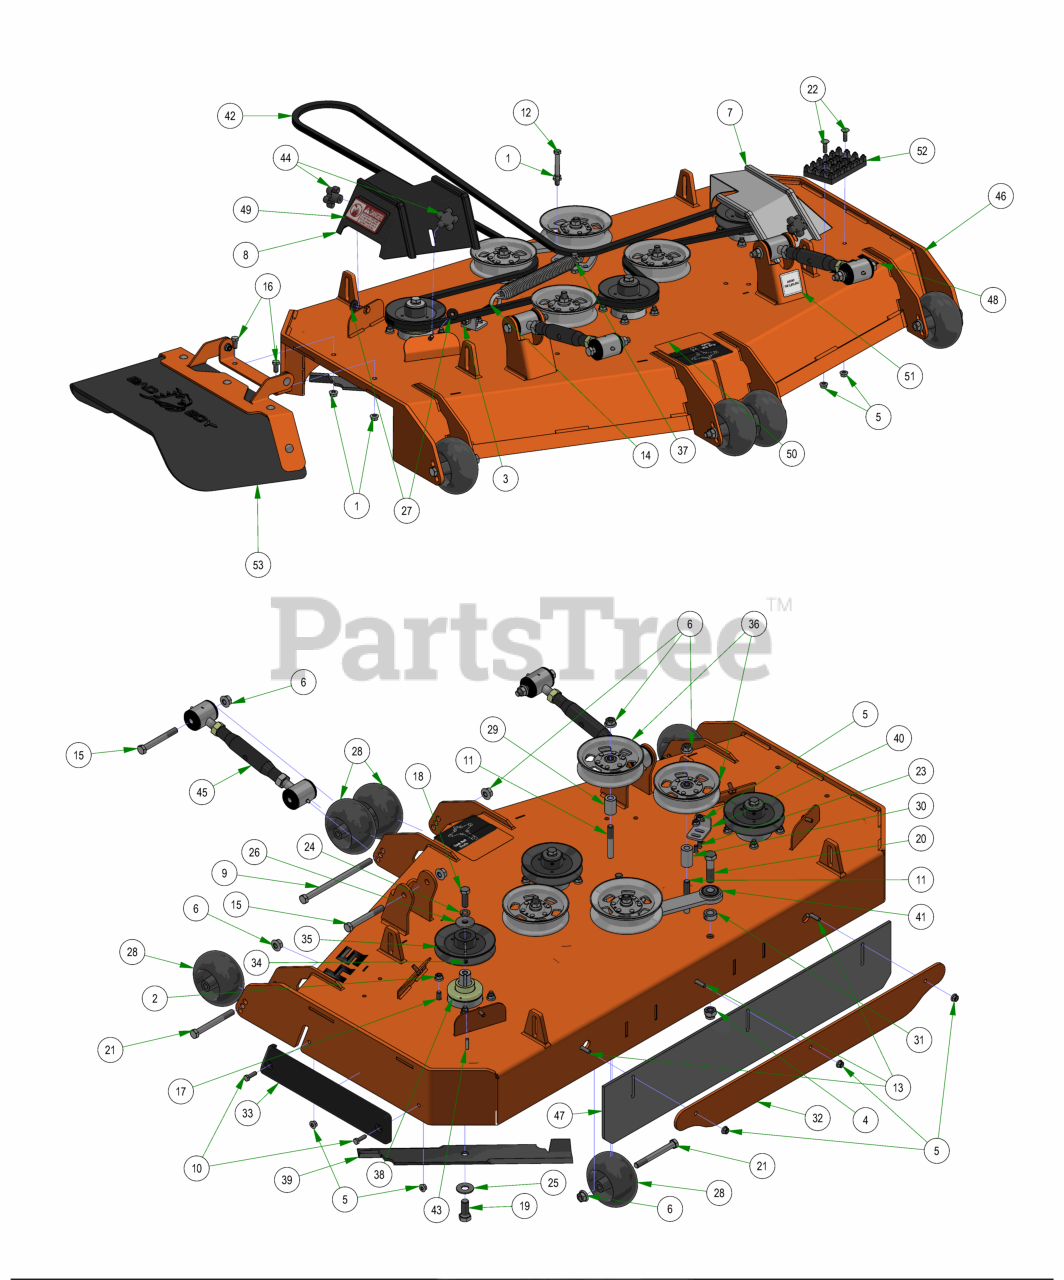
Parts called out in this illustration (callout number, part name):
1	3/8-16 HEX SERRATED FLANGE NUT HARD/ZINC
2	3/8-16 NYLON INSERT FLANGE LOCKNUT (GR.F) ZINC
3	3/8-16 HEX NUT ZINC
4	5/8-11 NYLON INSERT LOCKNUT ZINC
5	5/16-18 NYLON INSERT FLANGE LOCKNUT ZINC
6	1/2-13 NYLON INSERT FLANGE LOCKNUT ZINC
7	2019 54" Left Outlaw Gen2 Pulley Cover
8	2019 54" Right Outlaw Gen2 Pulley Cover
9	1/2-13 X 8 HEX CAP SCREW GR 5 ZINC
10	5/16-18 X 1 HEX CAP SCREW (GR.5) ZINC
11	1/2-13 X 3-1/2 HEX FLANGE BOLT (GR.8) ZINC
12	3/8-16 X 3 HEX CAP SCREW (GR.5) ZINC
13	5/16-18 X 1-1/4 CARRIAGE BOLT ZINC
14	4" 3/8-16 Eye Bolt
15	1/2-13 X 4 HEX CAP SCREW (GR.8) ZINC YELLOW
16	3/8-16 X 3/4 HEX CAP SCREW (GR.5) ZINC
17	3/8-16 X 1-1/2 HEX CAP SCREW (GR.5) ZINC
18	1/2-20 X 1-1/2 HEX CAP SCREW (GR.5) ZINC
19	5/8-18 X 1-1/2 HEX CAP SCREW (GR.8) ZINC YELLOW
20	5/8-11 X 2-1/2 HEX CAP SCREW (GR.5) ZINC
21	1/2-13 X 4-1/2 HEX CAP SCREW (GR.5) ZINC
22	5/16-18 X 1 CARRIAGE BOLT (GR.8) ZINC
23	5/16-18 X 7/8 CARRIAGE BOLT ZINC
24	1/2 SPLIT LOCKWASHER (GR.8) ZINC/YELLOW
25	5/8 USS FLAT WASHER (1-3/4" OD) GR.8 ZINC YELLOW
26	1/2 BELLEVILLE WASHER (1-5/8 OD X .140 THK) ZINC
27	.360 ID X .983 OD X .120 THICK FLAT WASHER NYLON BLACK
28	2019 Deck Wheel
29	.502 ID X .750 OD X 1.500 Long Spacer
30	1 3/4" Pulley Spacer
31	5/8 SOLID SHAFT COLLAR (W/1 SET SCREW) ZINC
32	61 Bolt in Baffle Deck v2 Stripping Plate
33	REVISED TRIM BUMPER_20180226
34	5/16-24 X 1/4 SOCKET SET SCREW (CUP PT) PLAIN
35	5.25" Deck Spindle Pulley
36	5-3/4 Idler Pulley
37	2019 Outlaw Gen2 Deck Spring
38	OUTLAW SPINDLE ASSEMBLY
39	54" Fusion Blade for Avenger/ZT/Mav/Outlaw/Revolt
40	2019 Deck Eye Bolt Tab
41	2019 Rebel Rogue Deck Idler
42	B165 Belt-60 54" deck Outlaw
43	1/4 X 1 SQ MACHINERY KEY 1018 STL PLN
44	5/16" Knob
45	Turnbuckle Assembly (M20-2.5)
46	2019 Sloped 54" Deck
47	R Series Rubber For Deck
48	54" Deck Decal
49	Danger Decal-Spindle/Discharge
50	2019 Rebel & Rogue Deck Belt Route Decal
51	Deck Impact Patent Decal 9591803
52	Deck Step Assembly
53	2019 Outlaw Gen2 Chute Assembly
